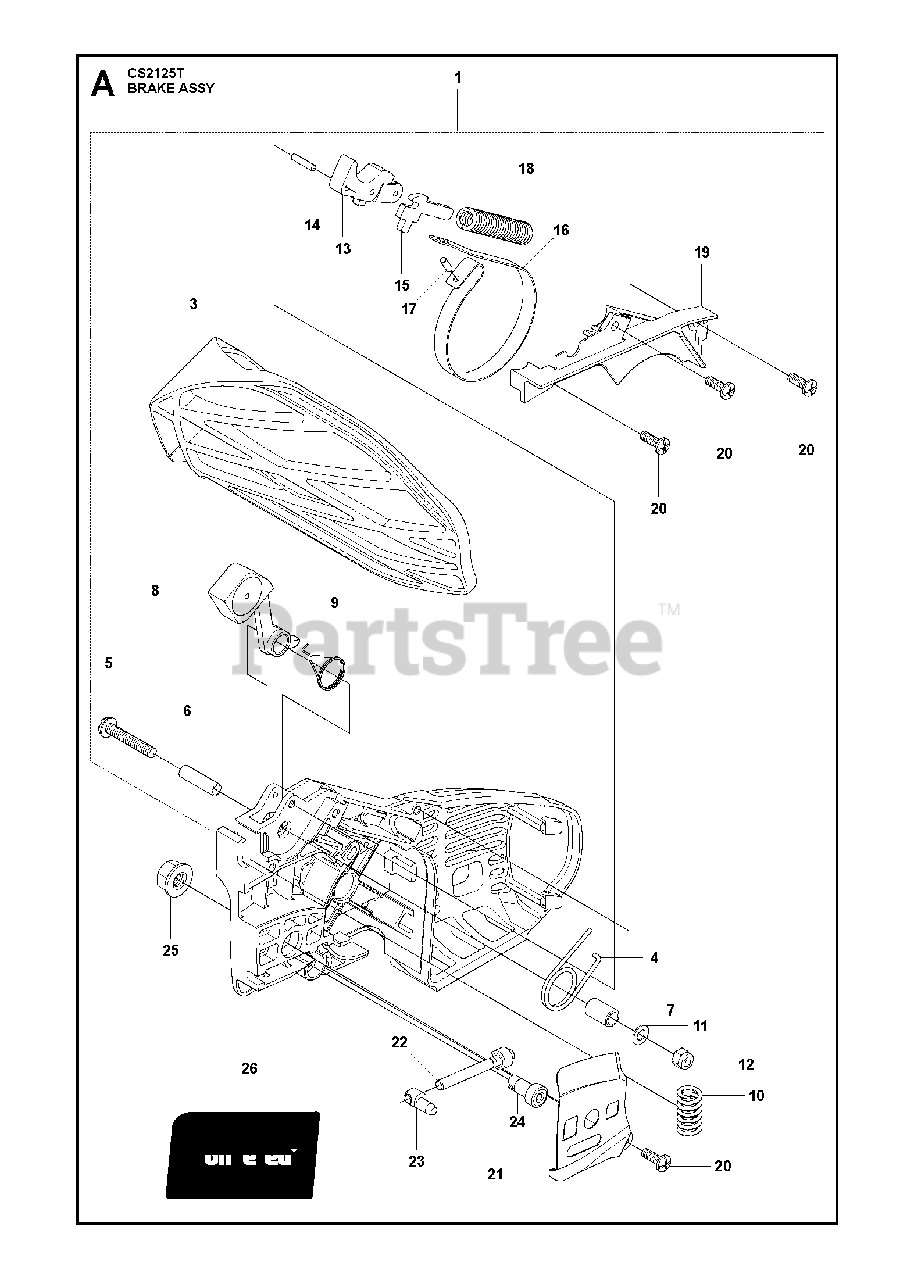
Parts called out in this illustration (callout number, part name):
12	NUT
14	ROLLER
15	ARM
18	SPRING
20	SCREW
